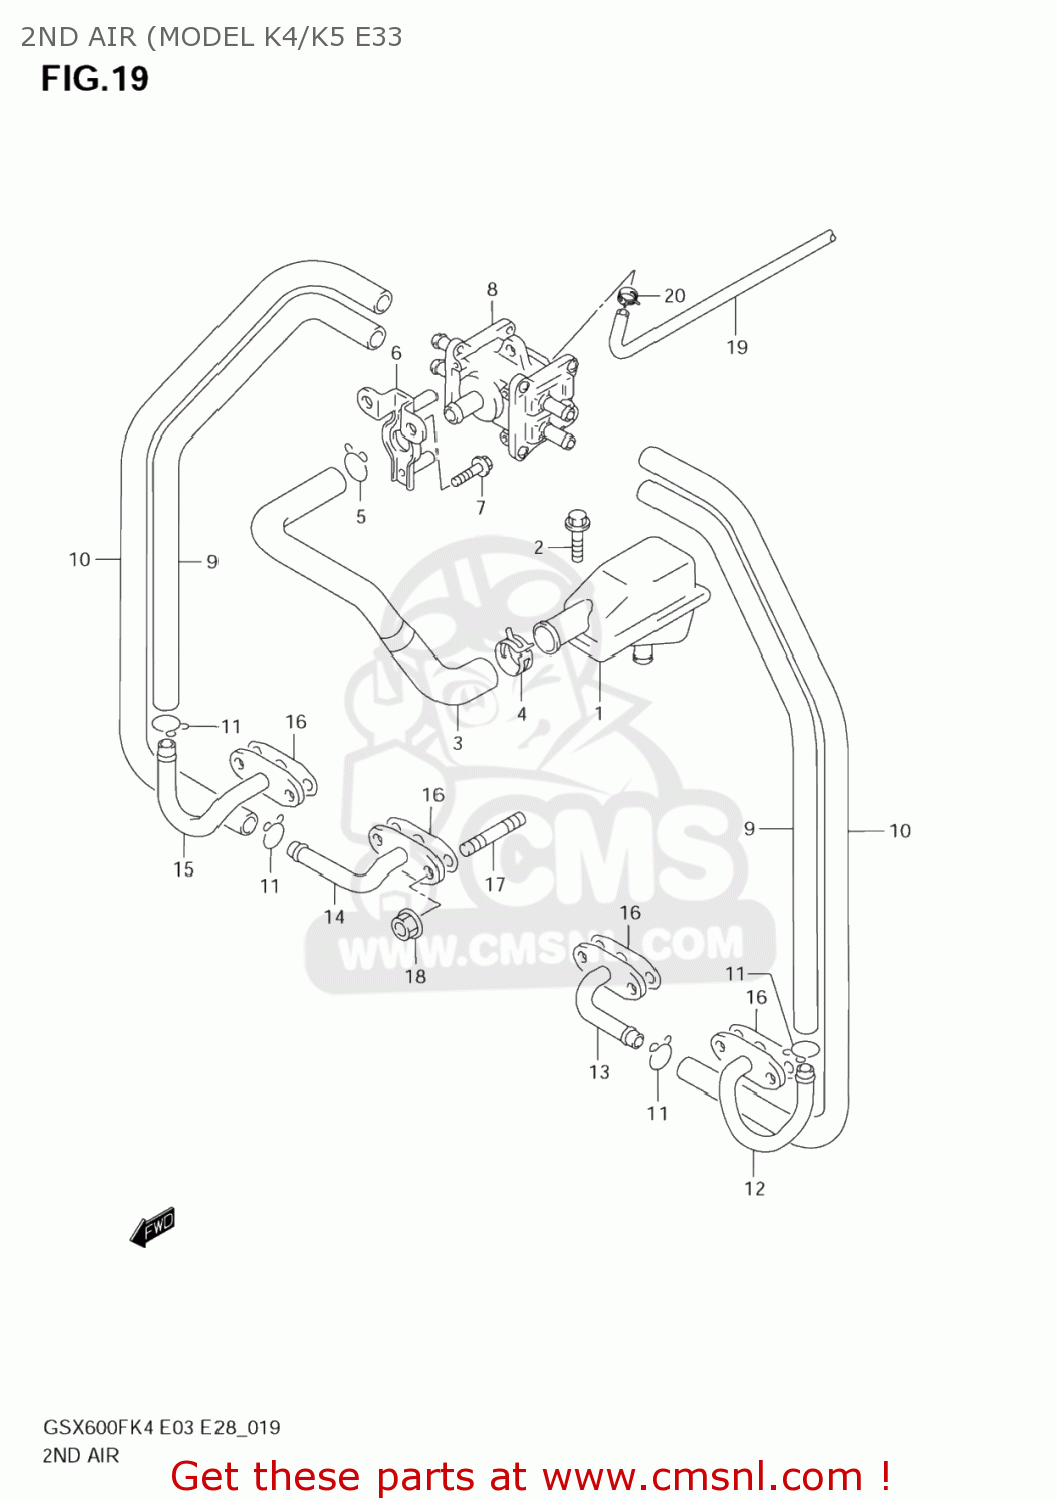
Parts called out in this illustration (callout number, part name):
1	CLEANER ASSY,2ND AIR
2	BOLT
3	HOSE,2ND AIR CLEANER
4	CLIP
5	CLIP
6	BRACKET,2ND AIR VALVE
7	BOLT
8	VALVE ASSY,2ND AIR
9	HOSE,2ND AIR VALVE OUTER
10	HOSE,2ND AIR VALVE INNER
11	CLIP
12	PIPE,2ND AIR NO.1
13	PIPE,2ND AIR NO.2
14	PIPE,2ND AIR NO.3
15	PIPE,2ND AIR NO.4
16	GASKET,2ND AIR PIPE (NAS)
17	STUD BOLT
18	NUT
19	HOSE(4.5X8.5X600)
20	CLIP
